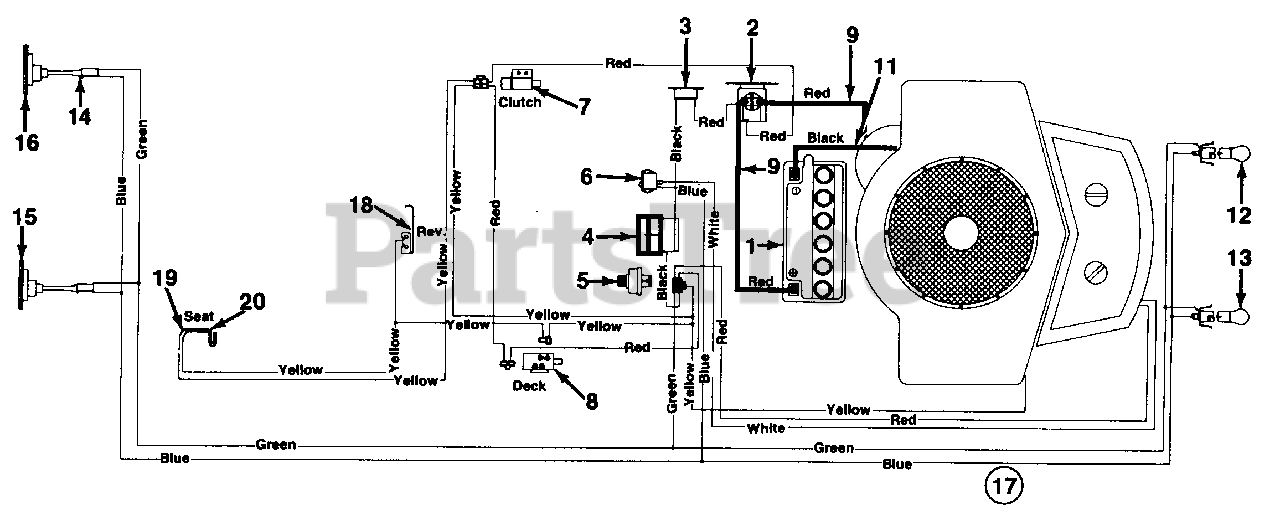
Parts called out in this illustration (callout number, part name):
1	Battery (275 Cold Crank Amps)
2	Solenoid
3	Circuit Breaker
4	Ammeter
5	Ignition Switch
6	Light Switch
7	Safety Switch
8	Safety Switch
9	Electric Wire 14" Lg.
11	Ground Wire 7.5" Lg.
12	Lamp
13	Socket
14	Taillight Harness
15	Taillight Ass'y.
16	Taillight Bulb
17	Wire Harness
18	Spring Switch
19	Safety Switch
20	Safety Switch
